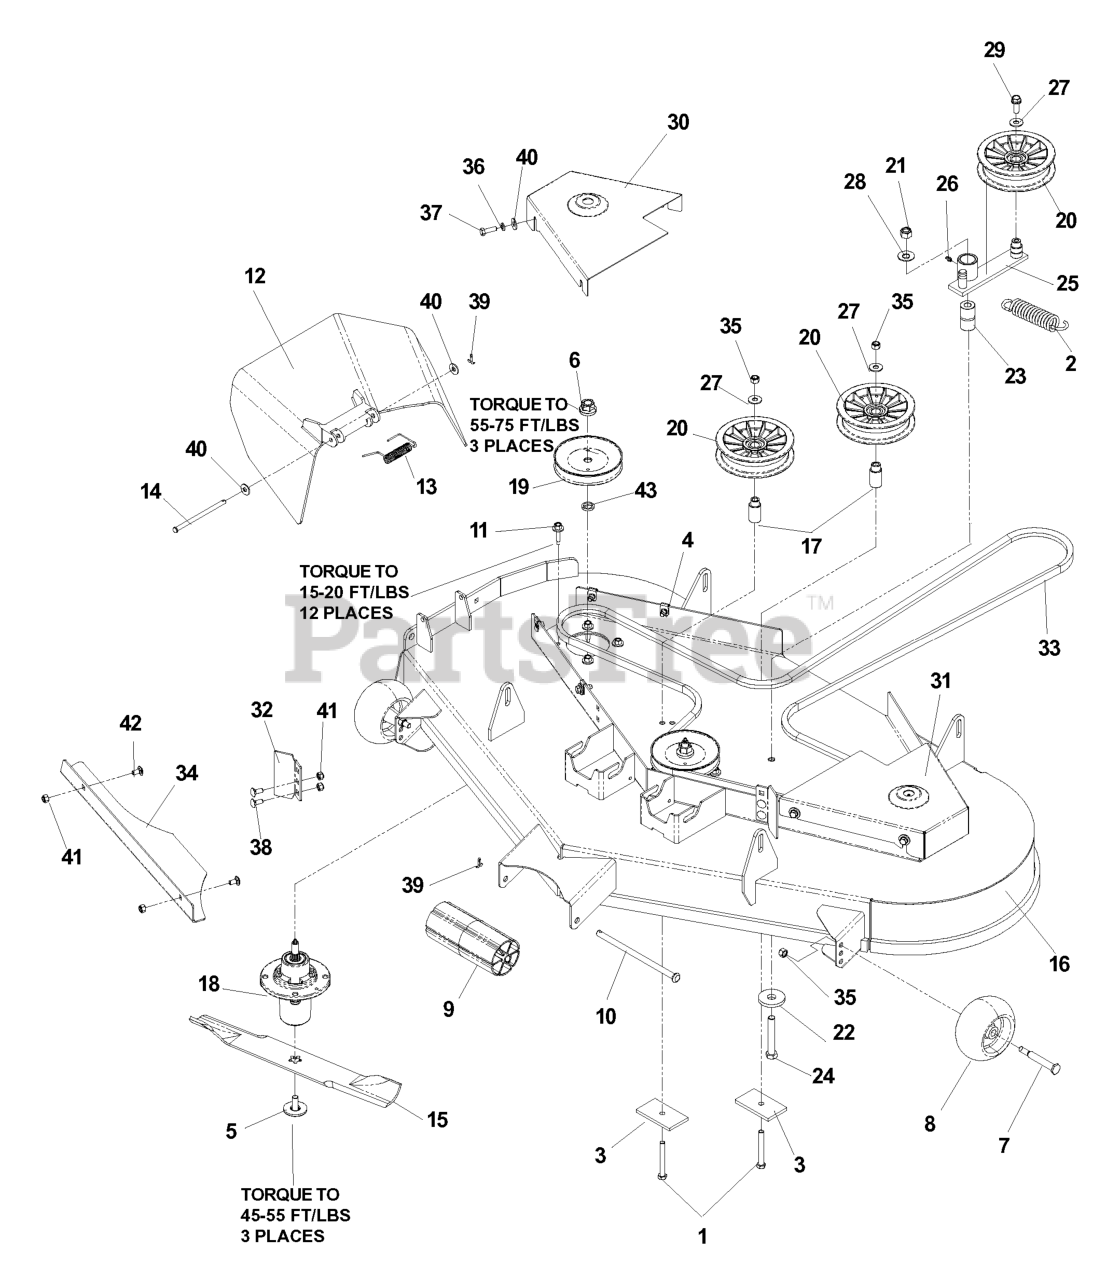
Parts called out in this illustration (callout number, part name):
1	HCS 3/8C X 3
3	SUPPORT PLATE
4	U-CLIP 5/16-18 NUT RETAINER
5	BOLT 7/16 ASM BLADE
6	LOCKNUT - 9/16
7	BOLT, SHOULDER
8	WHEEL GAGE DONUT
9	NOSE ROLLER 48"
10	NOSE ROLLER ROD
11	WASHER HEAD SCREW
12	DISCHARGE CHUTE 52"
13	SPRING - TORSION
14	PIN-CLEVIS 5/16 DIA X 5.19 ZD
15	BLADE, 18"
16	DECK W/DECALS 52"
17	IDLER BUSHING
18	MANDREL.DECK.ASSEMBLY
19	PULLEY
20	IDLER
21	NUT 1/2-13 HEX NYLOC ZD
22	WASHER, SUPPORT
23	PIVOT BUSHING
24	HCS 1/2C X 3 1/4
26	ZERK
27	WASHER 3/8 FLAT
28	WASHER 1/2 FLAT
29	4CS 3/8C X 1 SERRATED HEAD
30	BELT SHIELD, RIGHT 52, ORG
31	BELT SHIELD, LEFT 52, ORG
33	BELT, DECK 52"
34	CONFINEMENT PLATE, 52"
35	NUT 3/8-16 NYLOC
36	WASHER.LOCK.HVY.HLCL.SPR.5/16
37	HCS 5/16C X 1
38	BOLT 5/16C X 3/4" CARRIAGE
39	RP_COTTER PIN 1/8 X 3/4
40	WASHER 5/16 FLAT
41	NUT 5/16 NYLOC
42	CARRIAGE BOLT 5/16C X 5/8"
43	WASHER-SPACER
